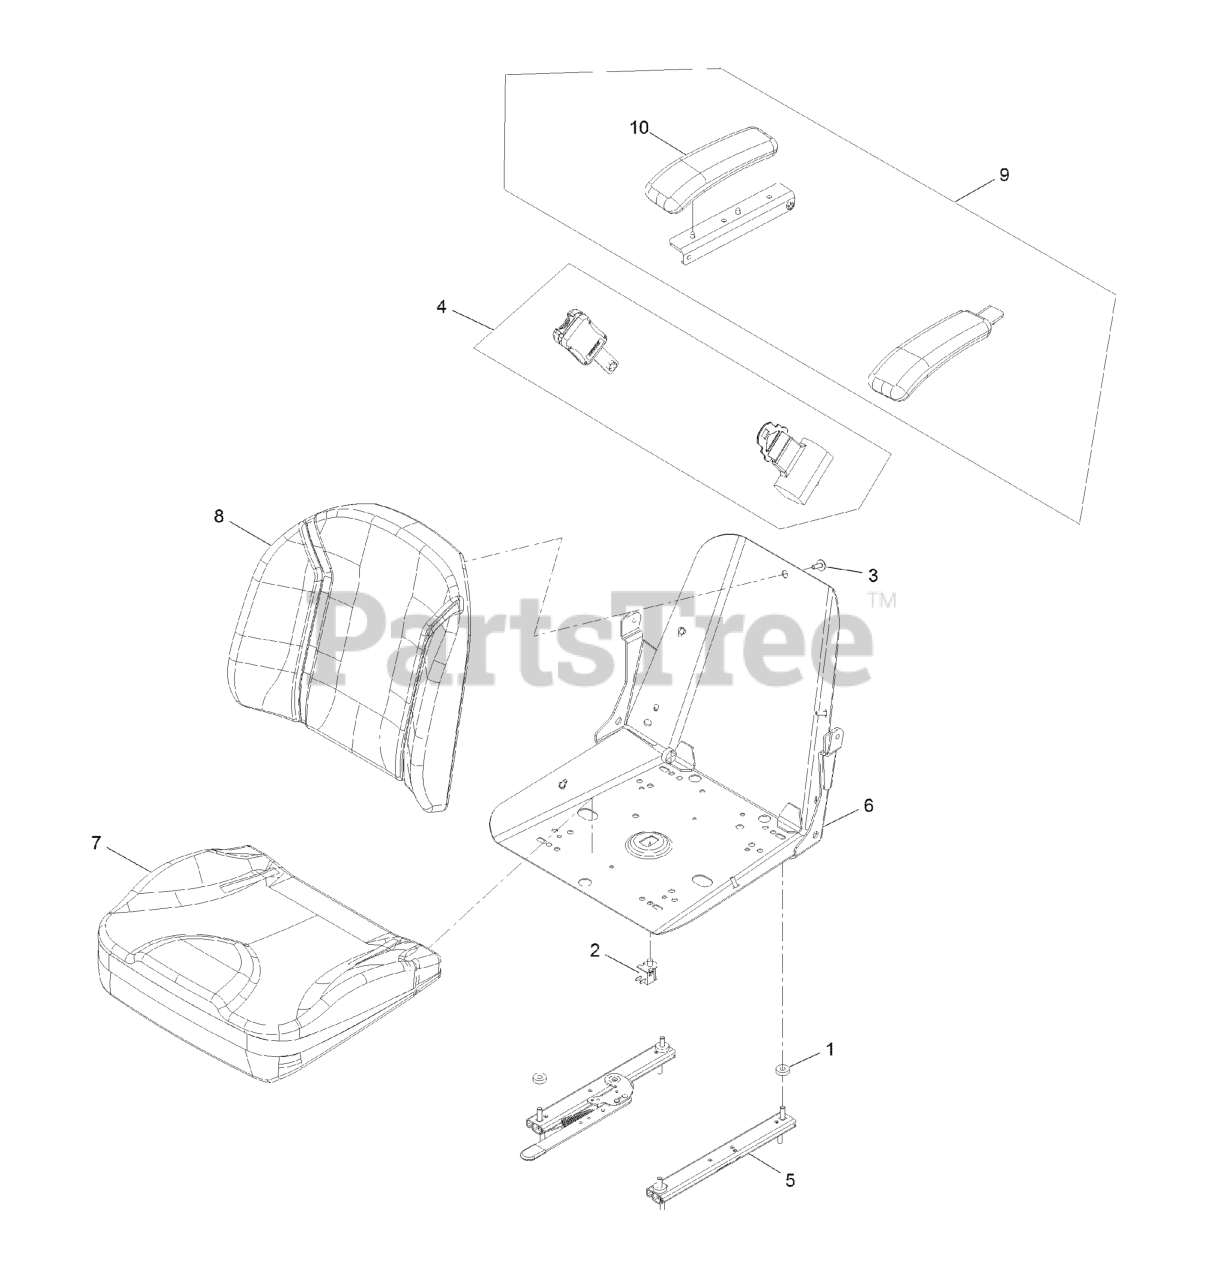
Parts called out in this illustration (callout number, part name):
2	SWITCH-BAIL
3	BOLT-SEAT
4	KIT-SEAT BELT
5	ASM-SEAT TRACK SVC
6	FRAME-SEAT SVC
7	COVER-SEAT BOTTOM SVC
8	CUSHION-SEAT, BACK
9	ARMREST KIT
10	CUSHION-REST, ARM
